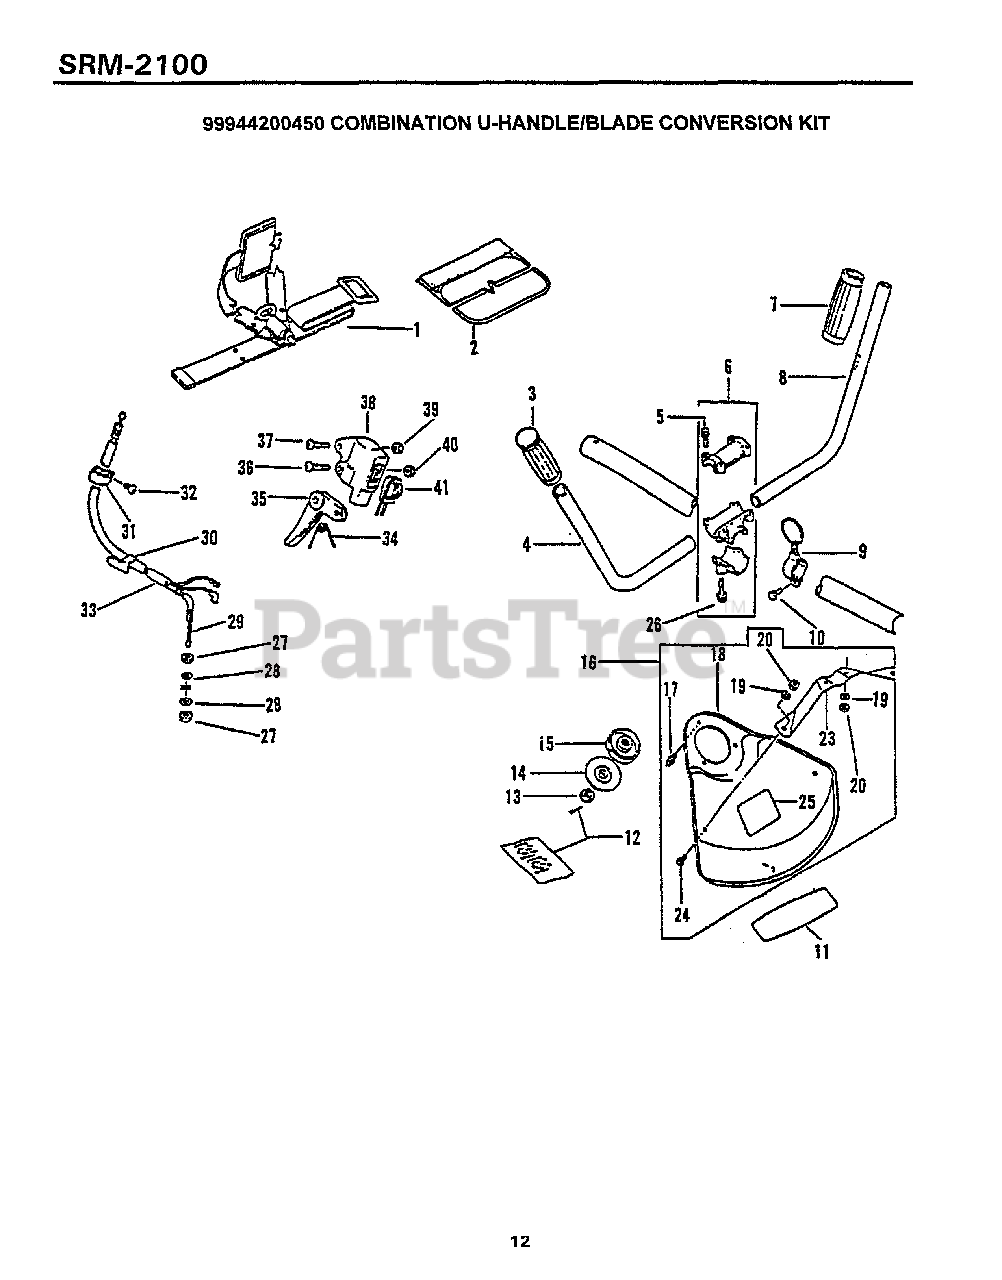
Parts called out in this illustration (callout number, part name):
1	SHOULDER STRAP ASSY
2	PAD, HIP
3	GRIP, HANDLE
4	HANDLE, LEFT
5	BOLT - 5×25
6	HANDLE BRACKET KIT
9	HOOK
10	BOLT 5×12
11	LABEL, ECHO
12	PIN, COTTER 2×22
14	PLATE, ADAPTOR - LOWER
15	PLATE, ADAPTER - UPPER
16	SHIELD ASSY
17	SCREW 5×10
18	SHIELD
19	WASHER, SPRING 5
20	NUT M5
23	BRACKET, SHIELD MOUNTING
24	SCREW 5×8
25	LABEL - CAUTION
26	BOLT - 6×30
27	NUT 6 MM
28	WASHER 6.5×11.5×0.8
29	CABLE, THROTTLE
32	SCREW 5×10
33	TUBE
35	TRIGGER, THROTTLE
36	SCREW 5×25
38	BRACKET, THROTTLE
39	NUT, LOCK M5
40	NUT M5
41	IGNITION SWITCH ASSY
